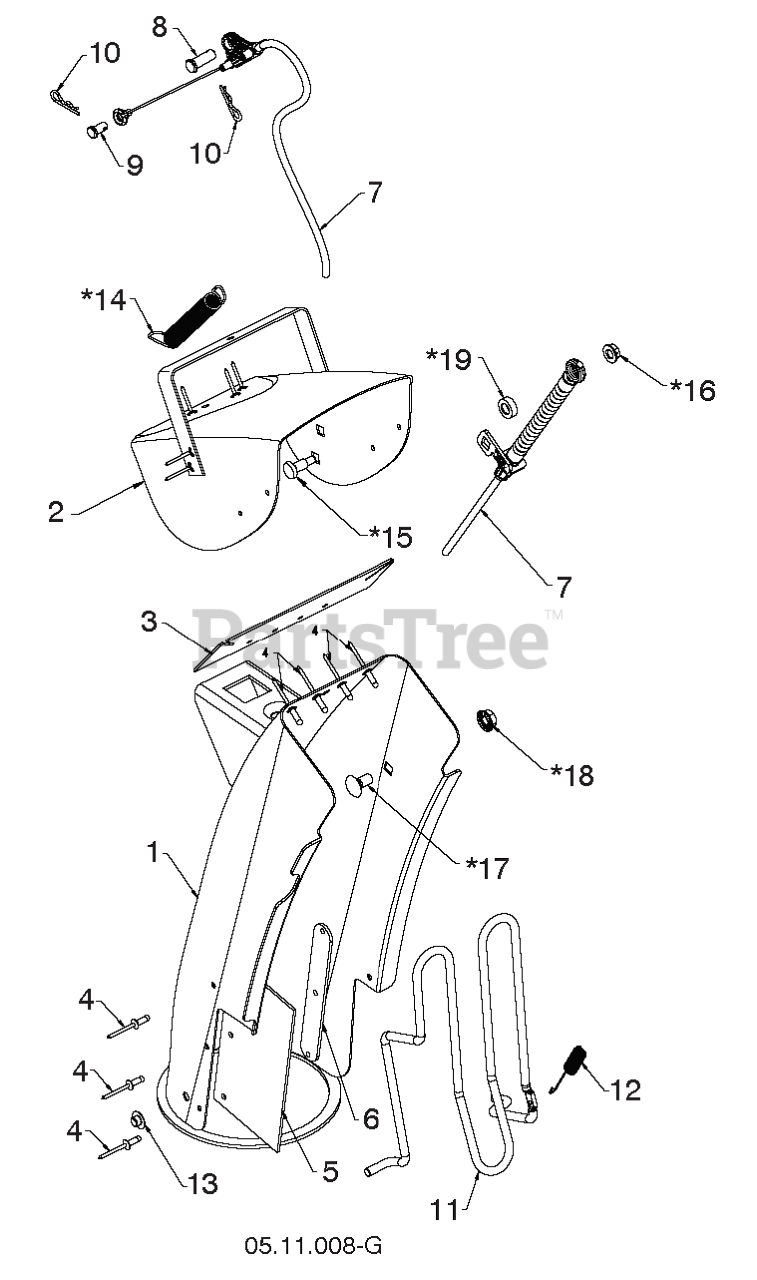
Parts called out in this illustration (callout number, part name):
1	ASM.CHUTE/DEFLECTOR.668
3	SEAL.DEFLECTOR
4	RIVET BLIND
5	SHIELD.SNOW.CHUTE
6	RP STRAP.SHEILD.RETAINER
7	CABLE.CONTROL.CHUTE.DEFLEC
8	PIN CLEVIS 5/16X.875
9	PIN CLEVIS .25 X .31
10	HAIRPIN.SOFT.ZINC.059X1.125
11	ROD.GUARD.CHUTE (2 2)
12	SPRING.CHUTE.GUARD
13	NUT
